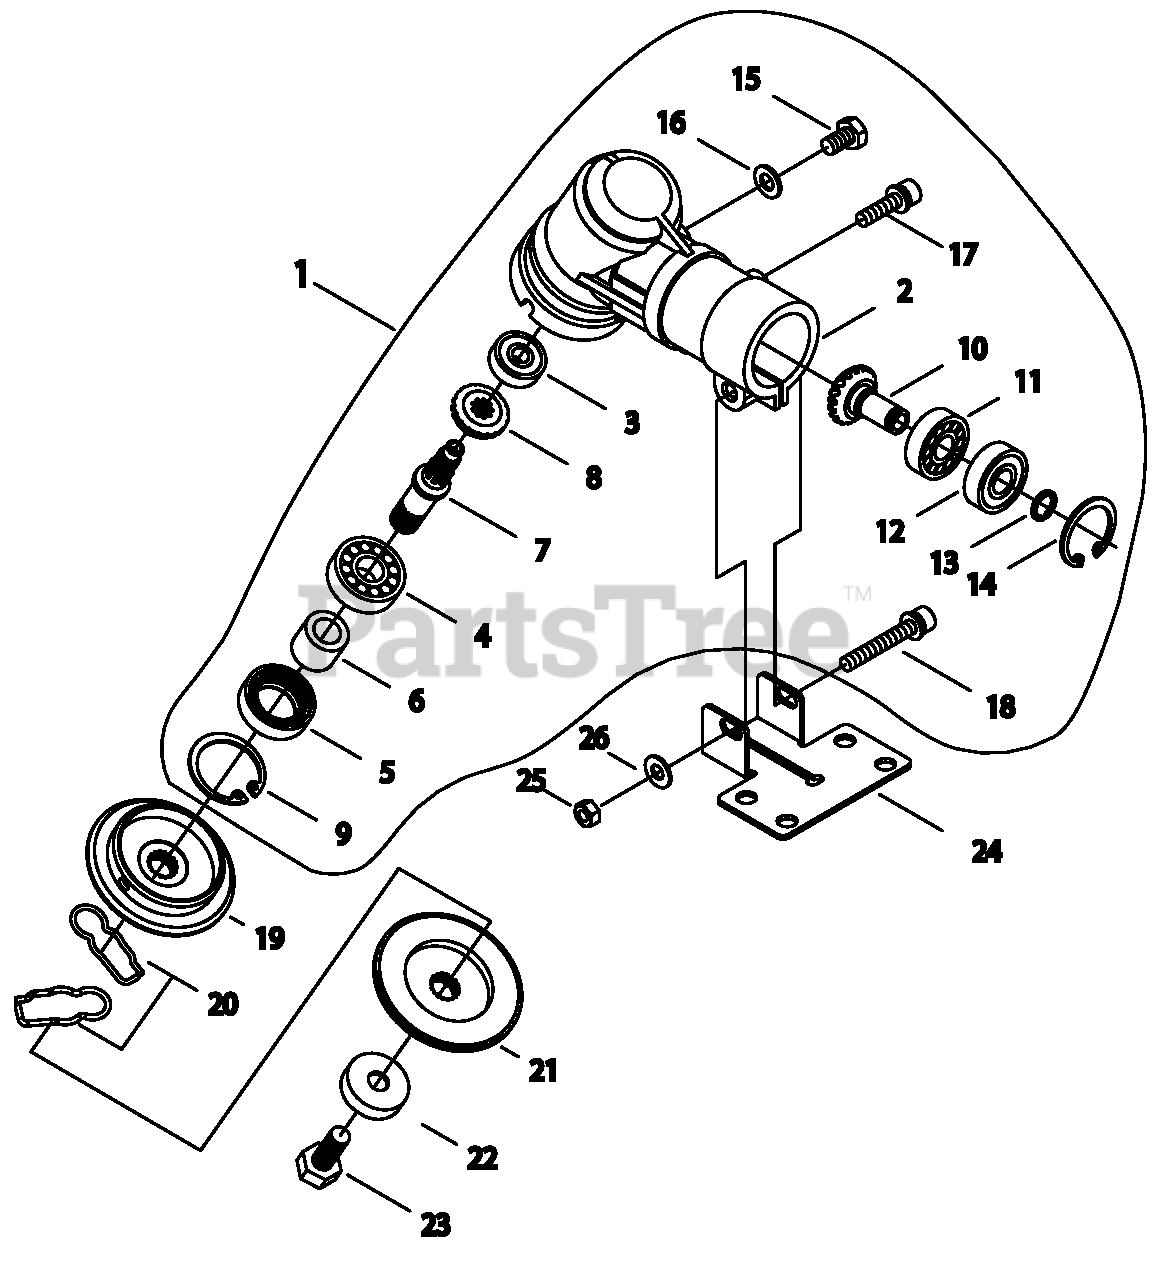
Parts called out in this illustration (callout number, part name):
1	GEAR CASE ASSY
2	HOUSING, GEAR CASE
3	BEARING, BALL 6000DDU
4	BEARING, BALL 6202
5	SEAL, OIL
6	COLLAR
7	SHAFT, GEAR
8	GEAR, BEVEL
9	RING, SNAP Ø35
10	PINION ASSY, BEVEL
11	BEARING, BALL 6001
12	BEARING, BALL 6001ZZ
13	RING, SNAP Ø12
14	RING, SNAP Ø28
15	BOLT M6×10
16	WASHER
17	BOLT M6×14
18	BOLT M6×40
19	PLATE, ADAPTOR - UPPER
20	PIN, SLIDE
21	HOLDER
22	GUARD, BOLT
23	BOLT 10×37
24	CLAMP, LOWER
25	NUT, HEX M6
27	WASHER
